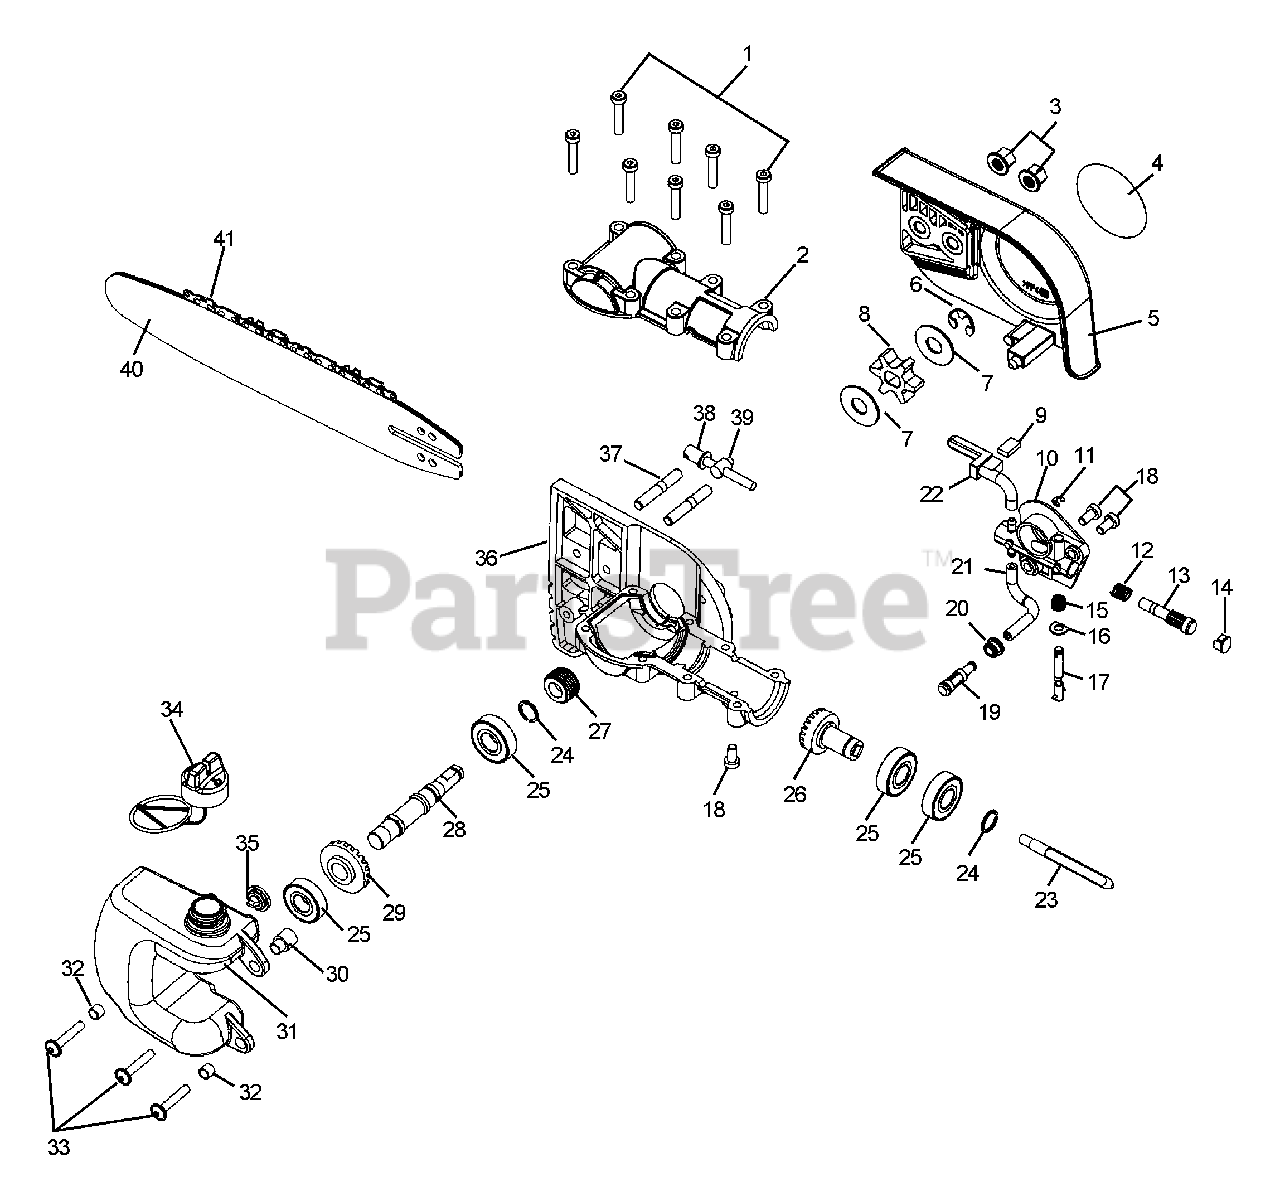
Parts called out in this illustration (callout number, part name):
1	SCREW M5×.25
2	CASE, GEAR - UPPER Ø35
3	NUT, FLANGE M6
4	LABEL, ECHO
5	GUARD, SPROCKET
6	RING, RETAINING Ø0.300
7	WASHER 10.2×24.5×1.2
8	SPROCKET, DRIVE
9	PAD, FOAM
10	AUTO-OILER ASSY
13	PLUNGER ASSY
14	CAP, OIL PUMP
17	ADJUSTER, OILER
18	SCREW M5×.8×10
19	FILTER, OIL
20	GROMMET
21	PIPE, IMPULSE 3×6×75
22	PIPE, OIL OUTLET
23	CONNECTOR, DRIVE SHAFT
24	RING, SNAP Ø12
25	BEARING, BALL 6201
26	GEAR, BEVEL
27	GEAR, WORM
28	SHAFT, GEAR
29	GEAR, BEVEL
30	COLLAR 6
31	TANK, OIL
32	SPACER 6.2×7.8×6
33	SCREW 5×28
34	CAP ASSY, OIL
35	VENT ASSY
36	CASE, GEAR
37	BOLT, STUD 6
39	TENSIONER, CHAIN
40	GUIDE BAR - 12"
41	SAWING CHAIN - 90SG - 12" -- MICRO-LITE
